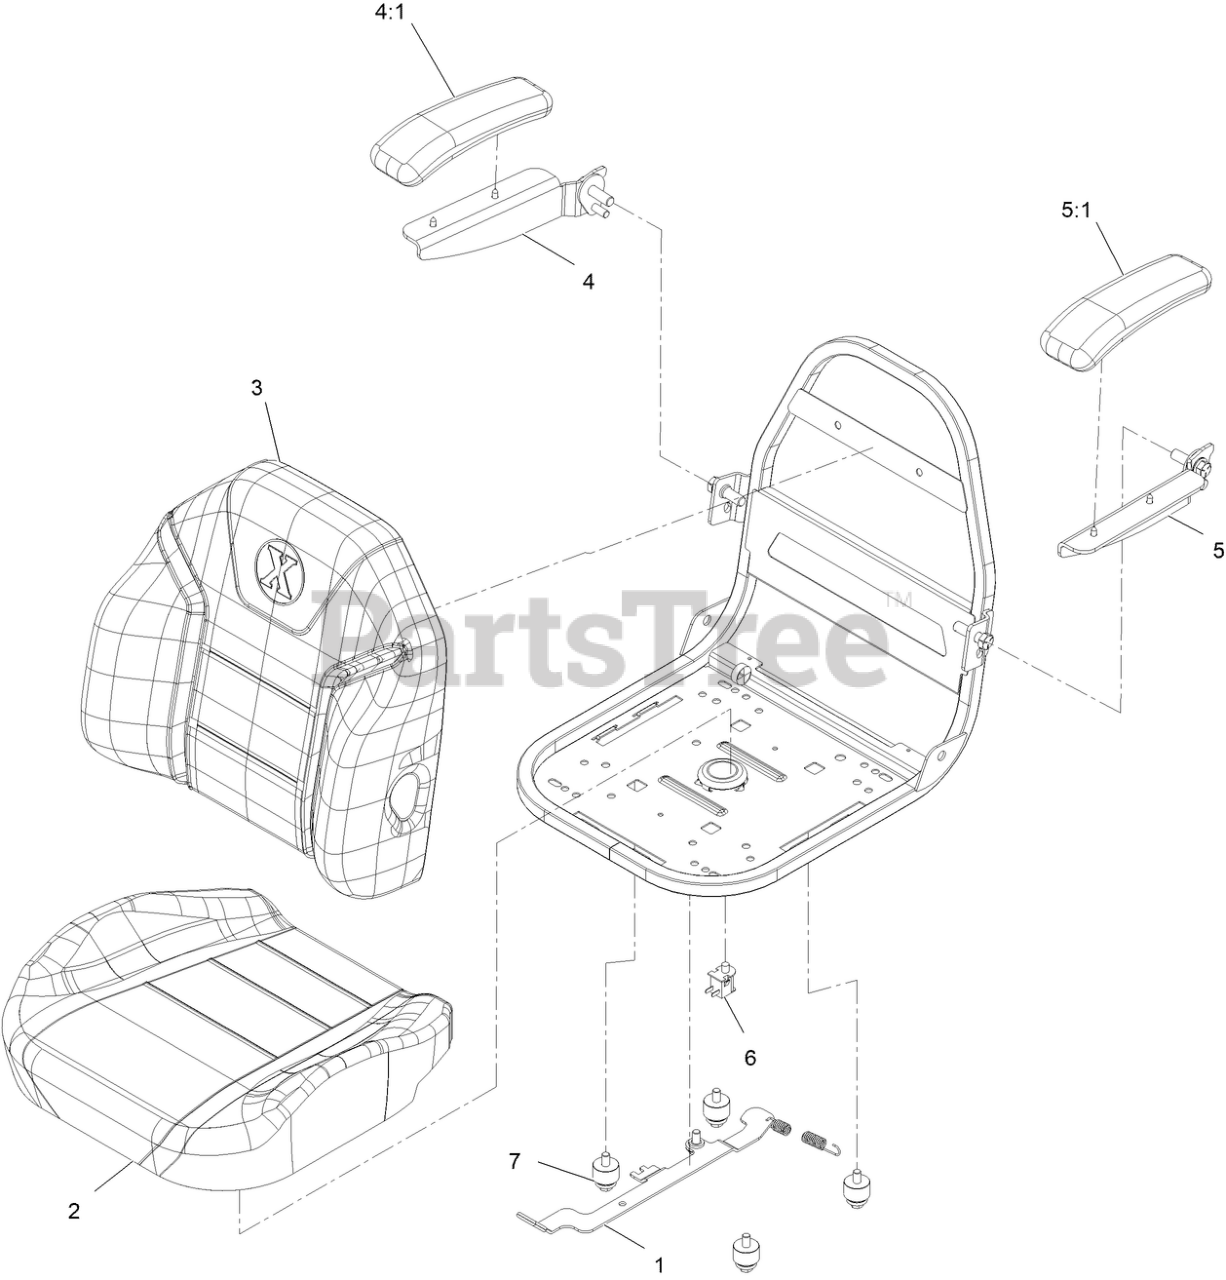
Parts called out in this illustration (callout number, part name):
1	TRACK ASM
2	COVER, LOWER
3	COVER, UPPER
4	RH Arm Rest Kit
4:1	CUSHION-REST, ARM
5	LH Arm Rest Kit
5:1	CUSHION-REST, ARM
6	SWITCH-BAIL
7	BUSHING ASM
